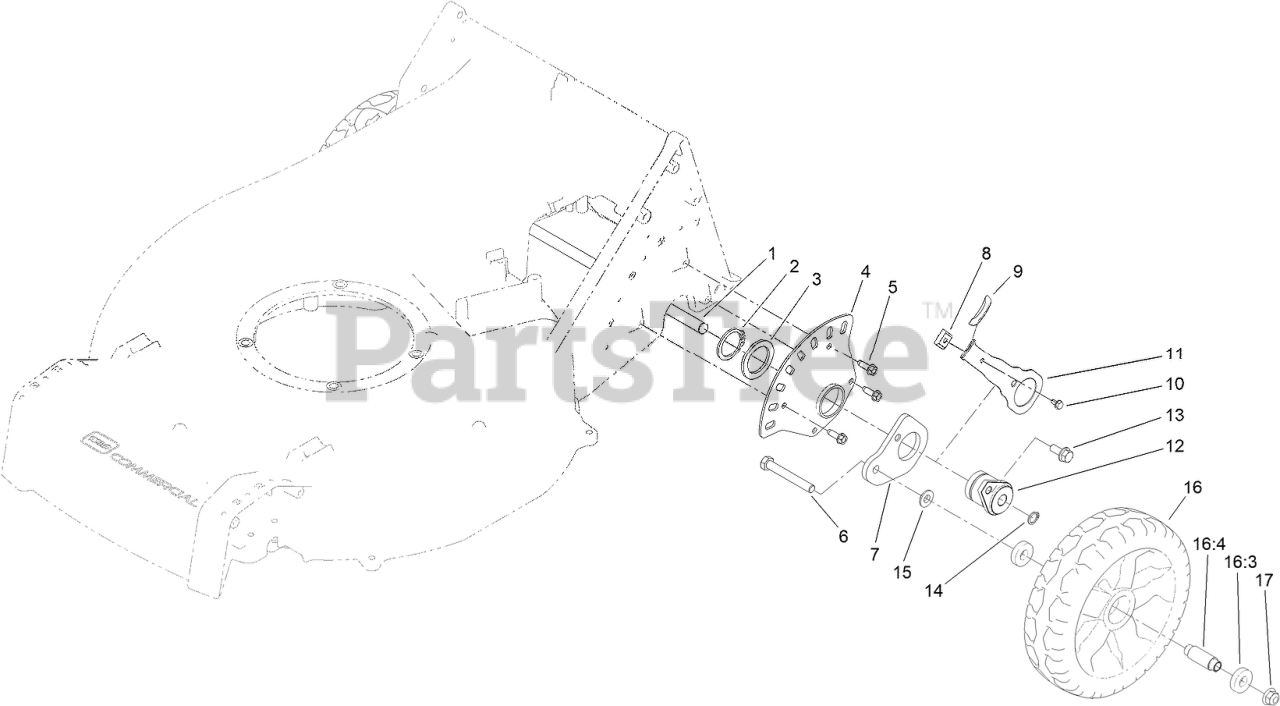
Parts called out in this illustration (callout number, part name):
1	SHAFT-REAR, HOC
2	RING-RETAINING
3	Washer-Thrust
4	PLATE-HOC, REAR
5	SCREW-HWHTF
6	SCREW-HH
7	ARM-PIVOT, REAR
8	KEY-ARM, SPRING
9	KNOB-LEVER, HOC
10	SCREW-HWH
11	ARM-SPRING, REAR
12	RETAINER-REAR, HOC
13	SCREW-HWH
14	RING-RETAINING
15	SPACER-COVER, WHEEL
16	WHEEL
16:3	BEARING-WHEEL
16:4	SPACER
17	NUT-HF, NI
